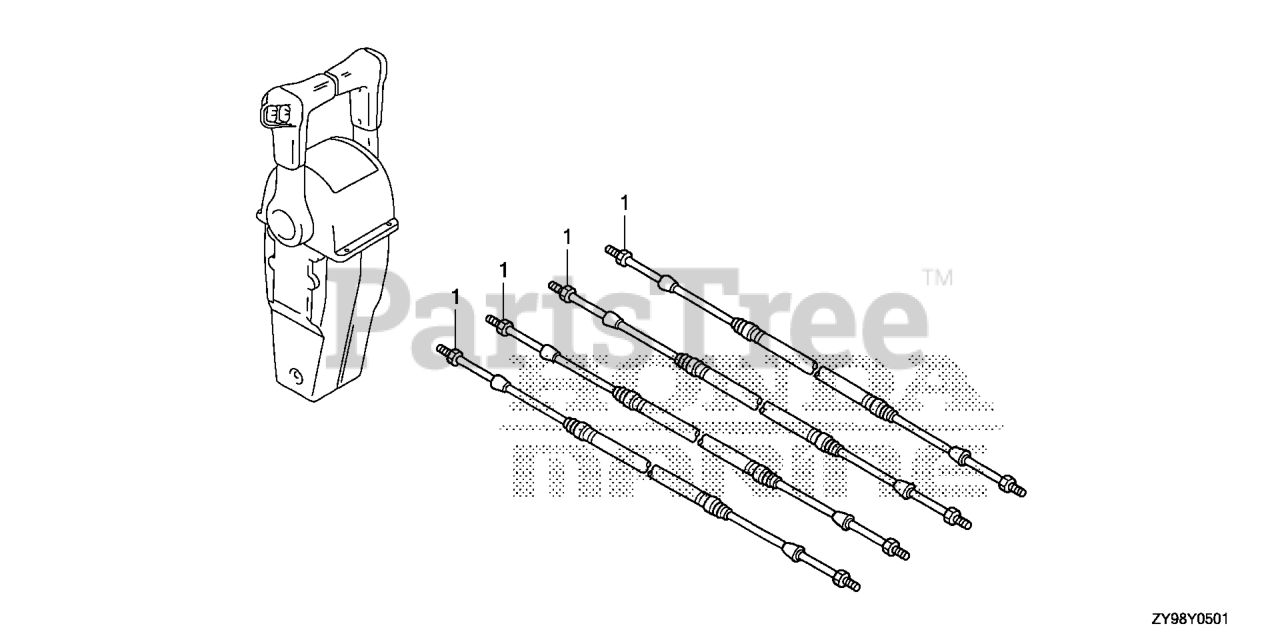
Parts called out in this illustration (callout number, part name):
1	CABLE, REMOTE CONTROL (5') (LOW FRICTION)
1	CABLE, REMOTE CONTROL (6') (LOW FRICTION)
1	CABLE, REMOTE CONTROL (7') (LOW FRICTION)
1	CABLE ASSY., PUSH-PULL (33HPC-7FT)
1	CABLE, REMOTE CONTROL (8') (LOW FRICTION)
1	CABLE, REMOTE CONTROL (9') (LOW FRICTION)
1	CABLE ASSY., PUSH-PULL (33HPC-9FT)
1	CABLE, REMOTE CONTROL (10'') (LOW FRICTION)
1	CABLE ASSY., PUSH-PULL (33HPC-10FT)
1	CABLE, REMOTE CONTROL (11'') (LOW FRICTION)
1	CABLE ASSY., PUSH-PULL (33C-6FT)
1	CABLE, REMOTE CONTROL (12'') (LOW FRICTION)
1	CABLE, REMOTE CONTROL (13'') (LOW FRICTION)
1	CABLE, REMOTE CONTROL (14'') (LOW FRICTION)
1	CABLE, REMOTE CONTROL (15'') (LOW FRICTION)
1	CABLE ASSY., PUSH-PULL (33C-10FT)
1	CABLE, REMOTE CONTROL (16'') (LOW FRICTION) (NOT AVAILABLE)
1	CABLE ASSY., PUSH-PULL (33C-11FT)
1	CABLE, REMOTE CONTROL (17'') (LOW FRICTION)
1	CABLE ASSY., PUSH-PULL (33HPC-17FT)
1	CABLE, REMOTE CONTROL (18') (LOW FRICTION) (NOT AVAILABLE)
1	CABLE ASSY., PUSH-PULL (33C-13 FT)
1	CABLE, REMOTE CONTROL (1 9'') (LOW FRICTION)
1	CABLE, REMOTE CONTROL (20'') (LOW FRICTION) (NOT AVAILABLE)
1	CABLE, REMOTE CONTROL (21') (LOW FRICTION)
1	CABLE, REMOTE CONTROL (22') (LOW FRICTION) (NOT AVAILABLE)
1	CABLE, REMOTE CONTROL (2 3'') (LOW FRICTION)
1	CABLE, REMOTE CONTROL (24') (LOW FRICTION) (NOT AVAILABLE)
1	CABLE, REMOTE CONTROL (25') (LOW FRICTION)
1	CABLE, REMOTE CONTROL (26') (LOW FRICTION)
1	CABLE ASSY., PUSH-PULL (33HPC-26FT)
1	CABLE ASSY., PUSH-PULL (33C-21FT)
1	CABLE, REMOTE CONTROL (27') (LOW FRICTION)
1	CABLE, REMOTE CONTROL (28') (LOW FRICTION) (NOT AVAILABLE)
1	CABLE ASSY., PUSH-PULL (33C-23FT)
1	CABLE, REMOTE CONTROL (2 9') (LOW FRICTION)
1	CABLE ASSY., PUSH-PULL (33C-24FT)
1	CABLE, REMOTE CONTROL (30') (LOW FRICTION) (NOT AVAILABLE)
1	CABLE, REMOTE CONTROL (31') (LOW FRICTION)
1	CABLE, REMOTE CONTROL (32') (LOW FRICTION) (NOT AVAILABLE)
1	CABLE ASSY., PUSH-PULL (33C-27FT)
1	CABLE, REMOTE CONTROL (33') (LOW FRICTION)
1	CABLE ASSY., PUSH-PULL (33C-28FT)
1	CABLE, REMOTE CONTROL (34') (LOW FRICTION)
1	CABLE ASSY., PUSH-PULL (33C-29FT)
1	CABLE, REMOTE CONTROL (35') (LOW FRICTION)
1	CABLE ASSY., PUSH-PULL (33C-32FT)
